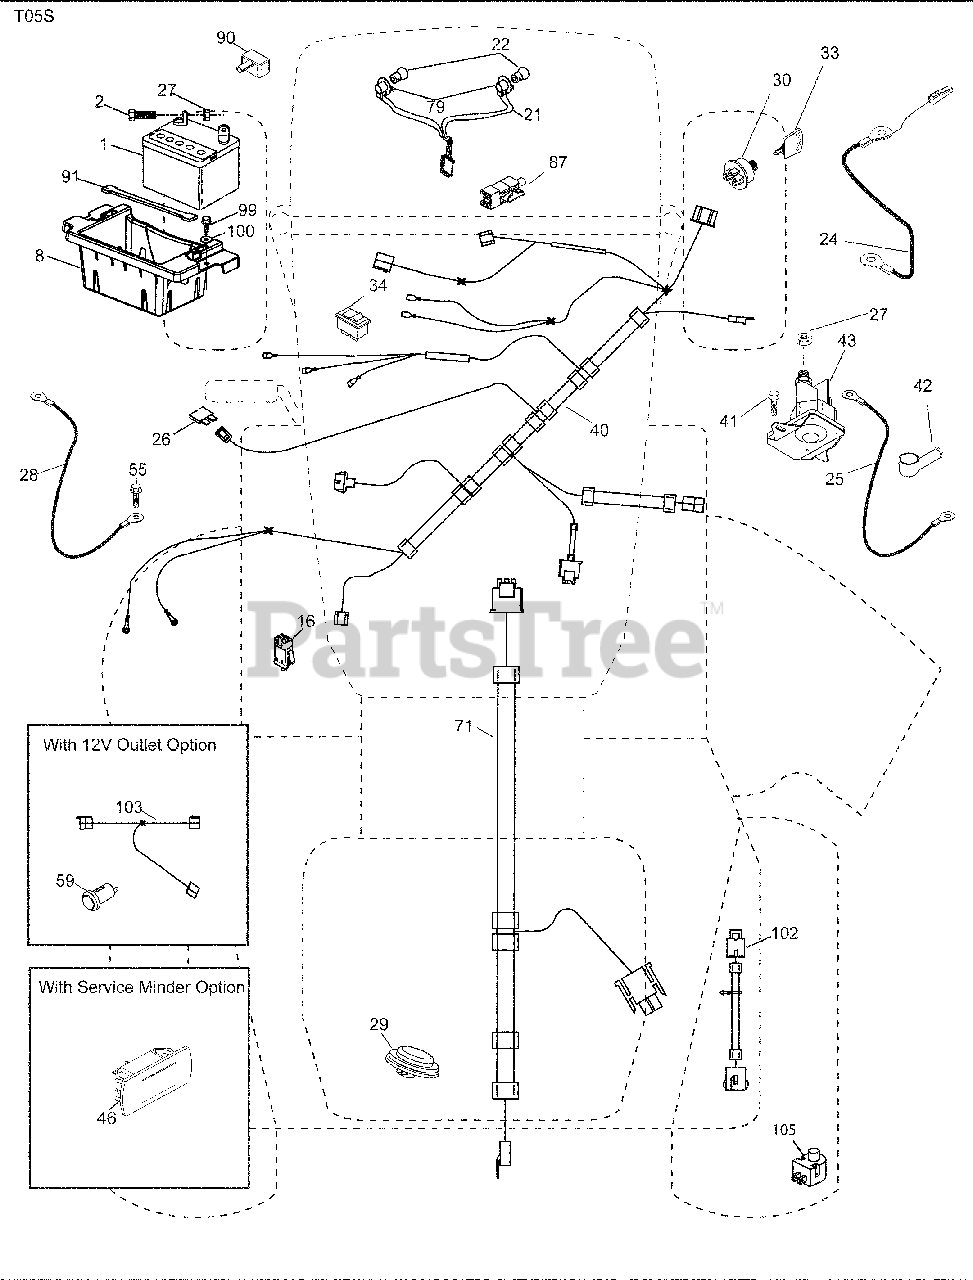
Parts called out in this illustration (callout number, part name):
1	Battery
2	Bolt Hex Hd 1/4-20 unc x 3/4
8	Battery Box
16	Switch Interlock
21	Harness Socket Light
22	Bulb, Light #1156
24	Cable Battery
25	Cable Starter
27	Nut Keps Hex 1/4-20 unc
28	Cable Ground 21" Blk 6 Ga.
29	Switch Seat
30	Switch Ign
34	Switch Light/Reset
40	Harness Ign. Dash
41	Screw Thd Cut 1/4-20 x 1/2
42	Cover Terminal Red
43	Solenoid
46	Gauge Hourmeter
55	Screw Thdrol 5/16-18 x 3/4
71	Harness Ign
79	Socket Asm. Bulb Twistlock
87	Switch Interlock
90	Cover Terminal Battery
91	Strap Battery
99	Screw Hexwsh Thdrol 1/4-20 x 3/4
100	Washer 9/32 x 7/8 x 16 Ga.
102	Harness Pigtail K46 Tex ROS
105	Switch reverse TT
